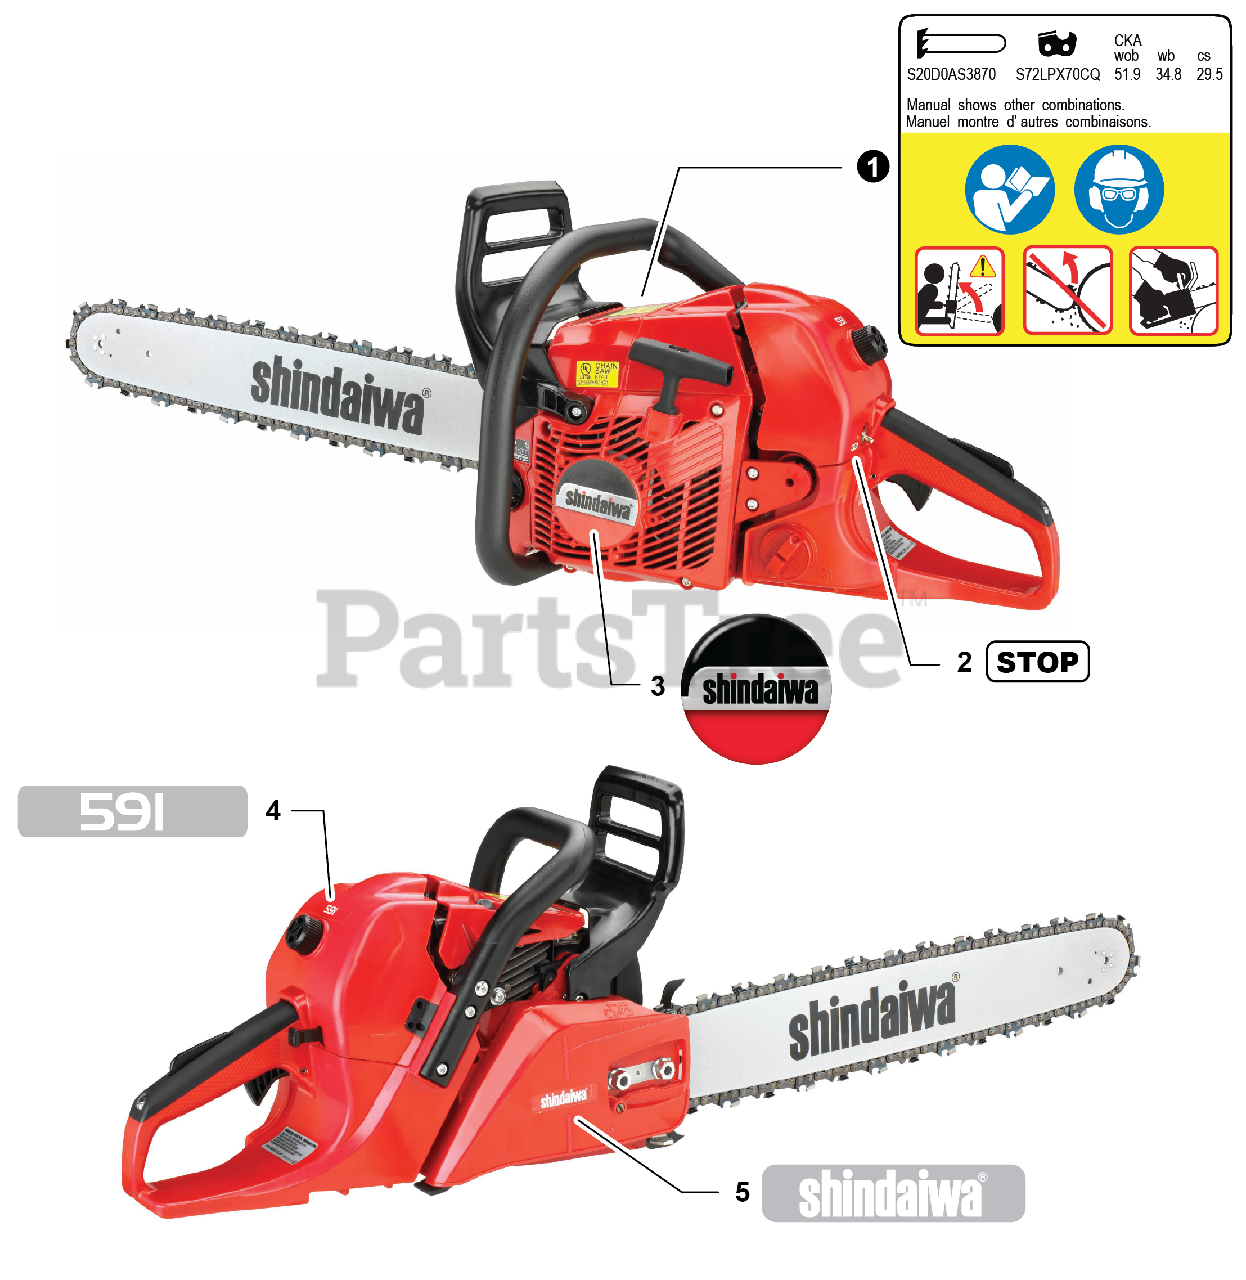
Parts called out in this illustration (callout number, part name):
1	LABEL, CAUTION
2	LABEL, STOP
3	LABEL, STARTER - SHINDAIWA
4	LABEL - MODEL 591
5	LABEL - SHINDAIWA
